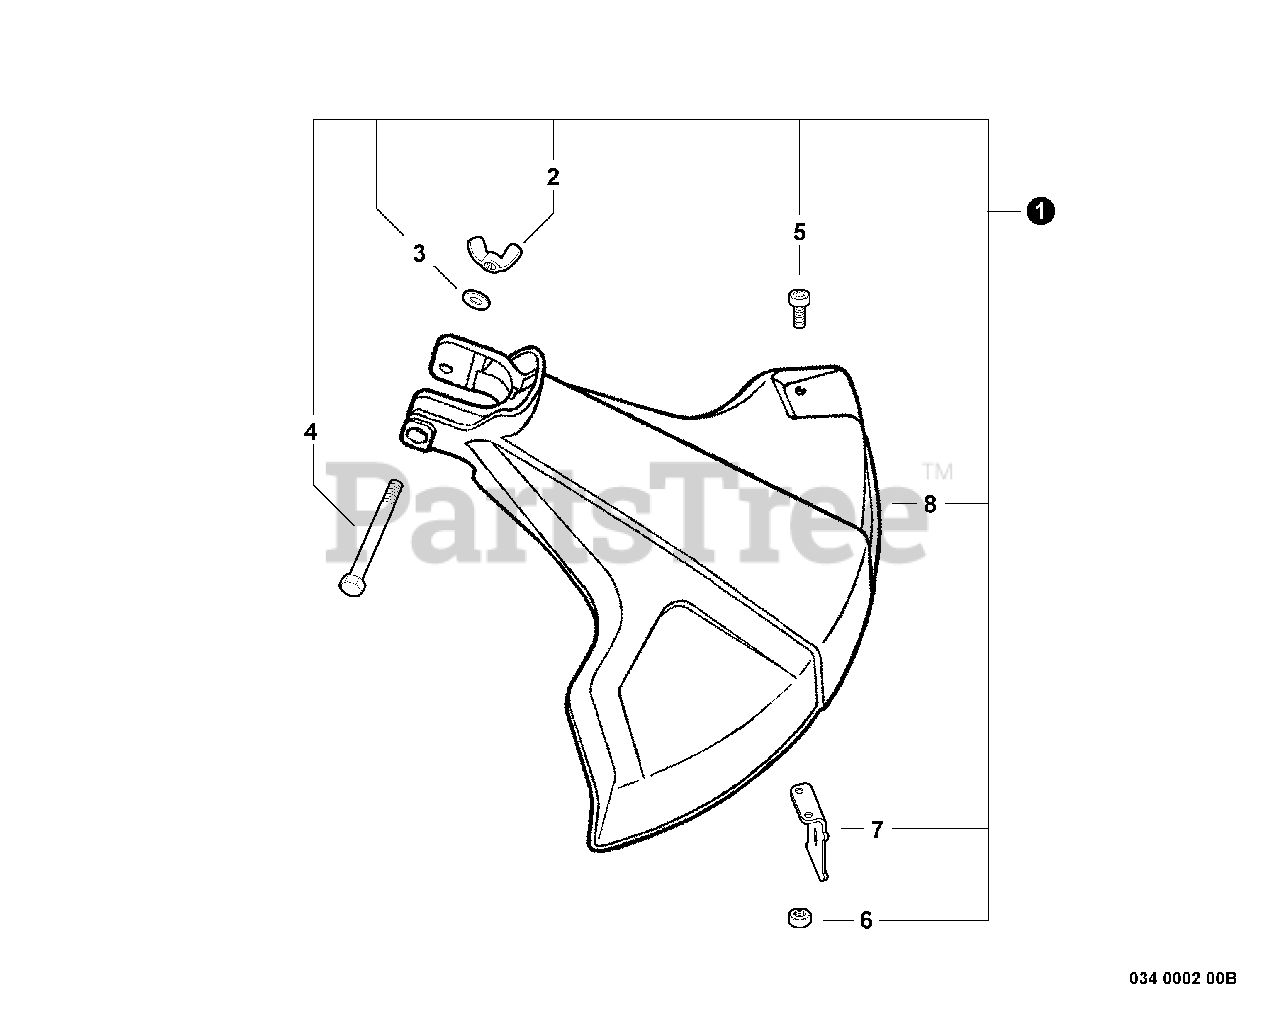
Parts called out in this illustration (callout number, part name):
1	DEBRIS SHIELD ASSY
2	NUT, WING 1/4"-20
3	WASHER, 1/4"
4	BOLT 1/4"-20×2"
5	BOLT, TORX 5×12
6	NUT M5
7	CUTTER, LINE
8	SHIELD, DEBRIS
